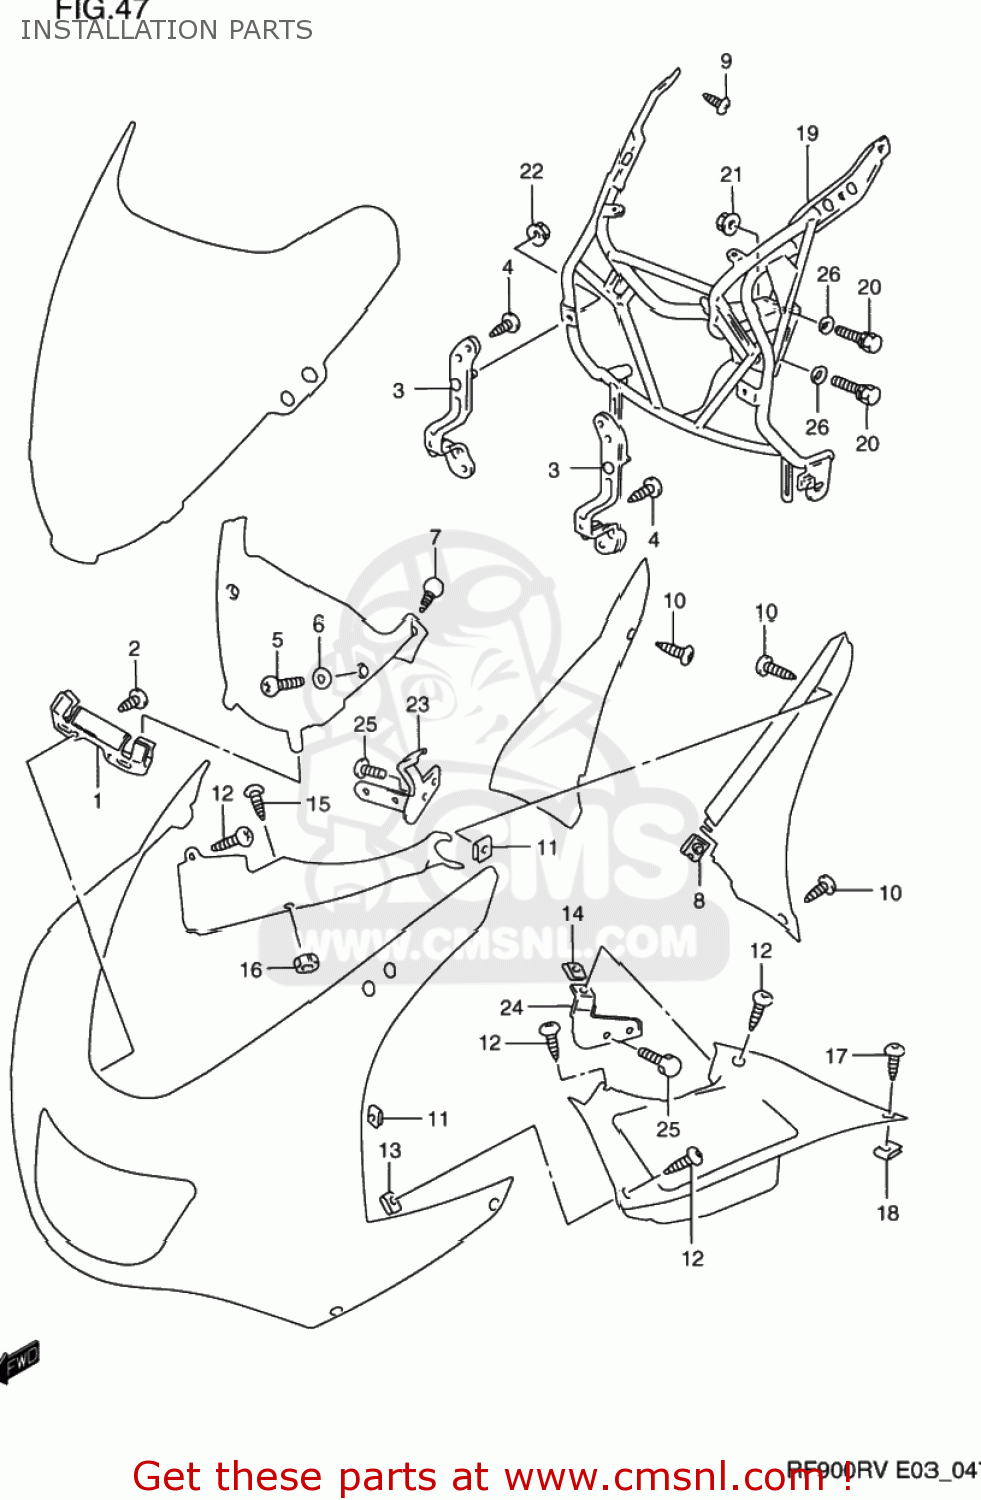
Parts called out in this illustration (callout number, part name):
1	SCREW
2	NUT
3	SCREW 5X10
4	SCREW
5	WASHER(5.2X14X1.5)
6	NUT,HEADLAMP HOUSING,UPPER
7	SCREW 5X10
8	SCREW
9	WASHER(5.2X14X1.5)
10	NUT,HEADLAMP HOUSING,UPPER
11	SCREW
12	WASHER(5.2X14X1.5)
13	NUT,HEADLAMP HOUSING,UPPER
14	CUSHION
15	SCREW
16	WASHER(5.2X14X1.5)
17	NUT,HEADLAMP HOUSING,UPPER
18	BOLT
19	SPACER(6.5X9X10)
20	CUSHION
21	BOLT
22	SPACER(6.5X9X10)
23	CUSHION
24	BRACKET,UNDER COWLING LWR,R
25	BRACKET,UNDER COWLING LWR,L
26	BOLT
27	BOLT
28	SPACER(6.1X10X16)
29	SCREW 5X12
30	WASHER(5.2X14X1.5)
31	BRACKET,RR UNDER COWLING FTG
32	NUT
33	SCREW
34	WASHER(5.2X14X1.5)
35	NUT,HEADLAMP HOUSING,UPPER
36	BRACKET,UNDER COWLING UPR,R
37	BRACKET,UNDER COWLING UPR,L
38	CUSHION,UNDER PANEL
